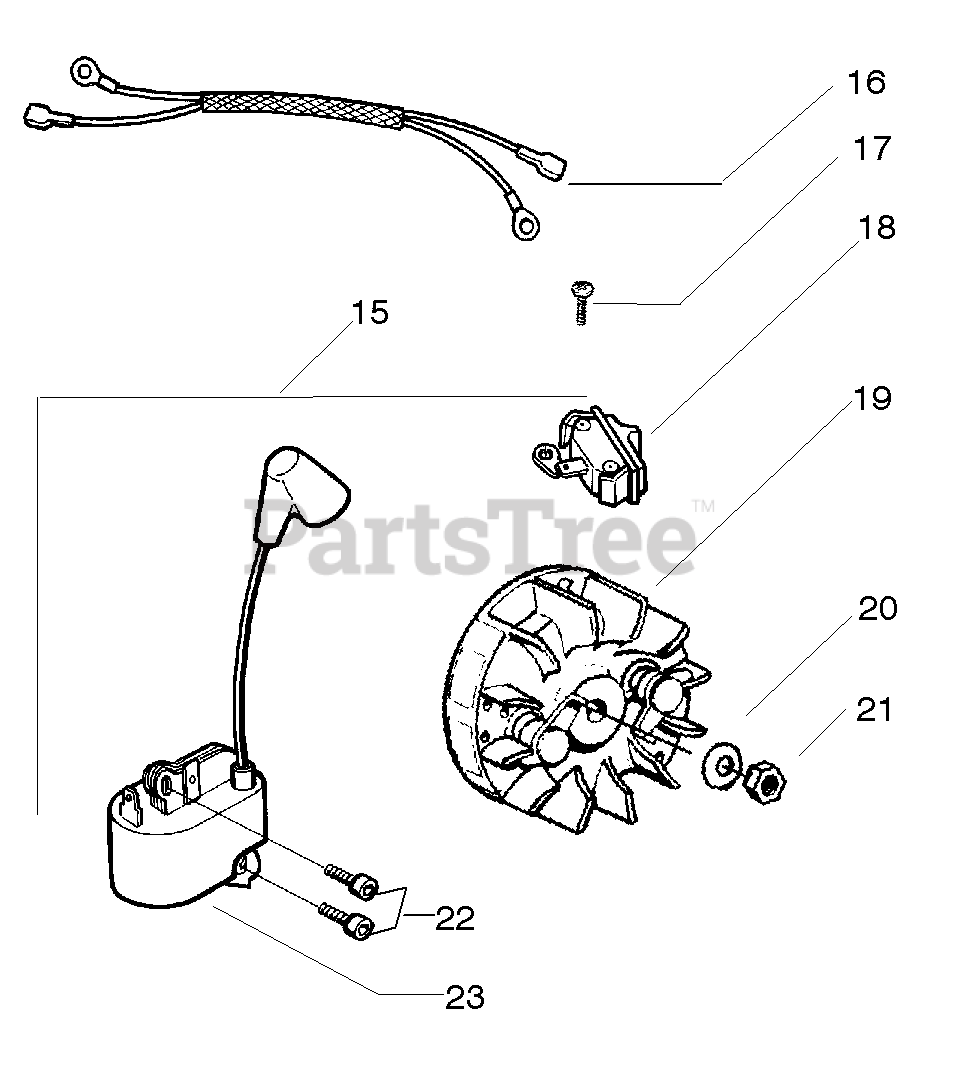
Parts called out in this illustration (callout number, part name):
15	Kit-EPS ignition
16	Assy-Leadwire
18	Switch-Ignition
19	Assy. -Flywheel
20	Washer-Flywheel
23	Module - Ignition
